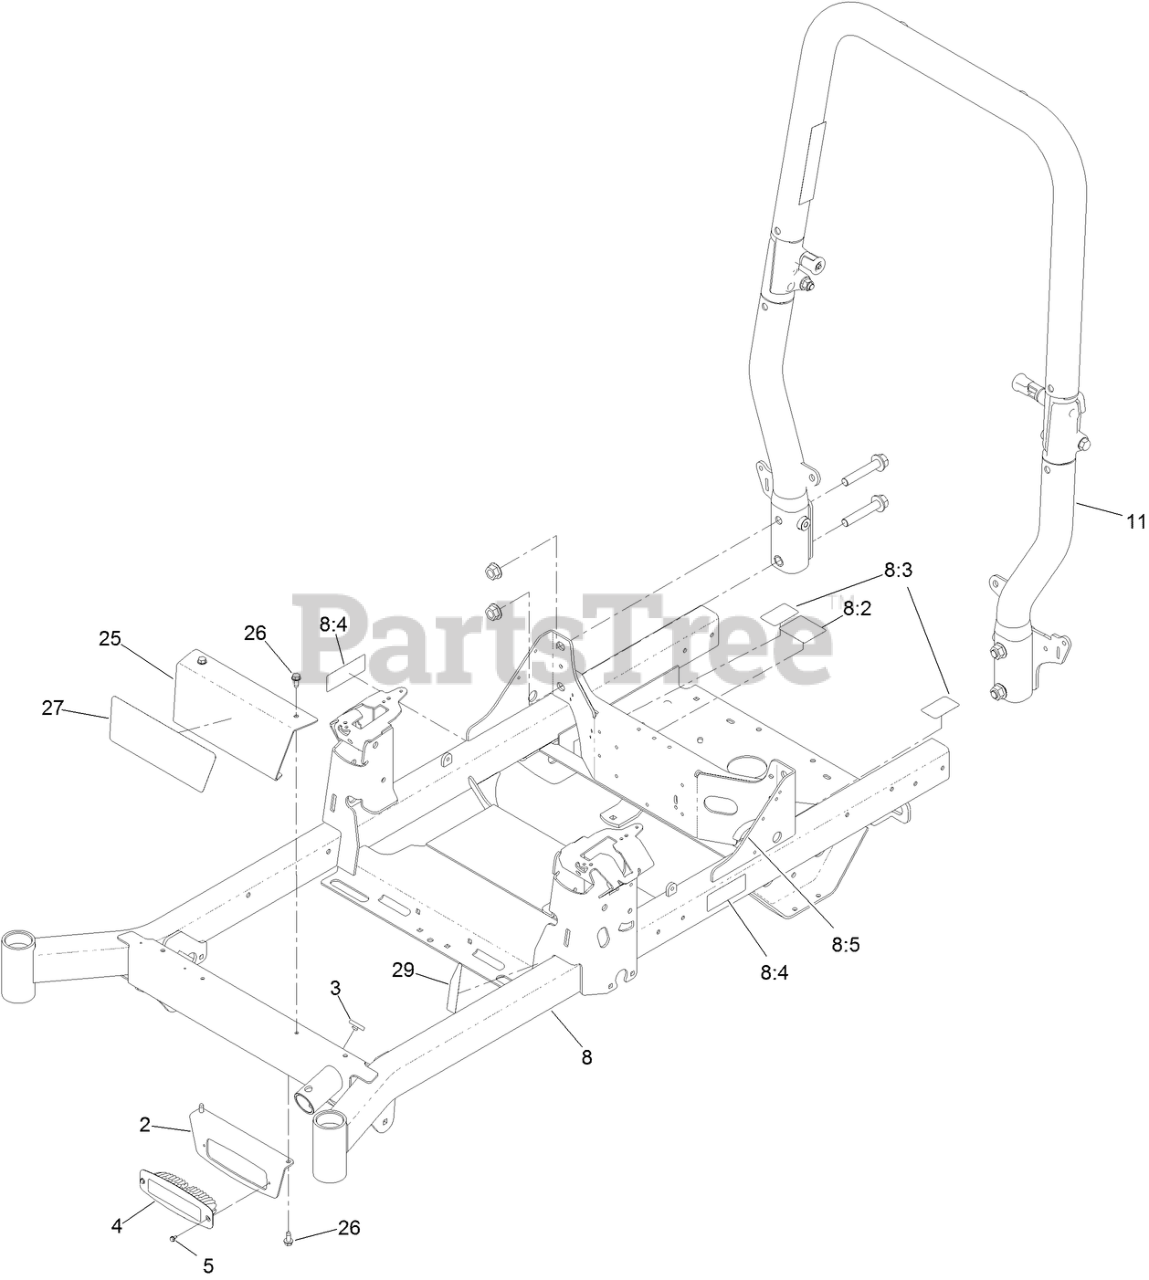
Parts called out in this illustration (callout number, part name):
2	BRACKET-LIGHT
3	BUMPER-PUSH-IN, RUBBER
4	MOUNT-FLUSH, LIGHT
5	SCREW-HWH
8	SUSPENSION FRAME ASM
8:2	DECAL-ROUTING, BELT
8:3	DECAL-RELEASE, DRIVE
8:4	DECAL-WARNING
8:5	STRIP-SEAL
11	ROPS ASM
25	PLATE-FRONT
26	SCREW-HWHTF
27	DECAL-Z MASTER
29	DECAL-FILL, FUEL
